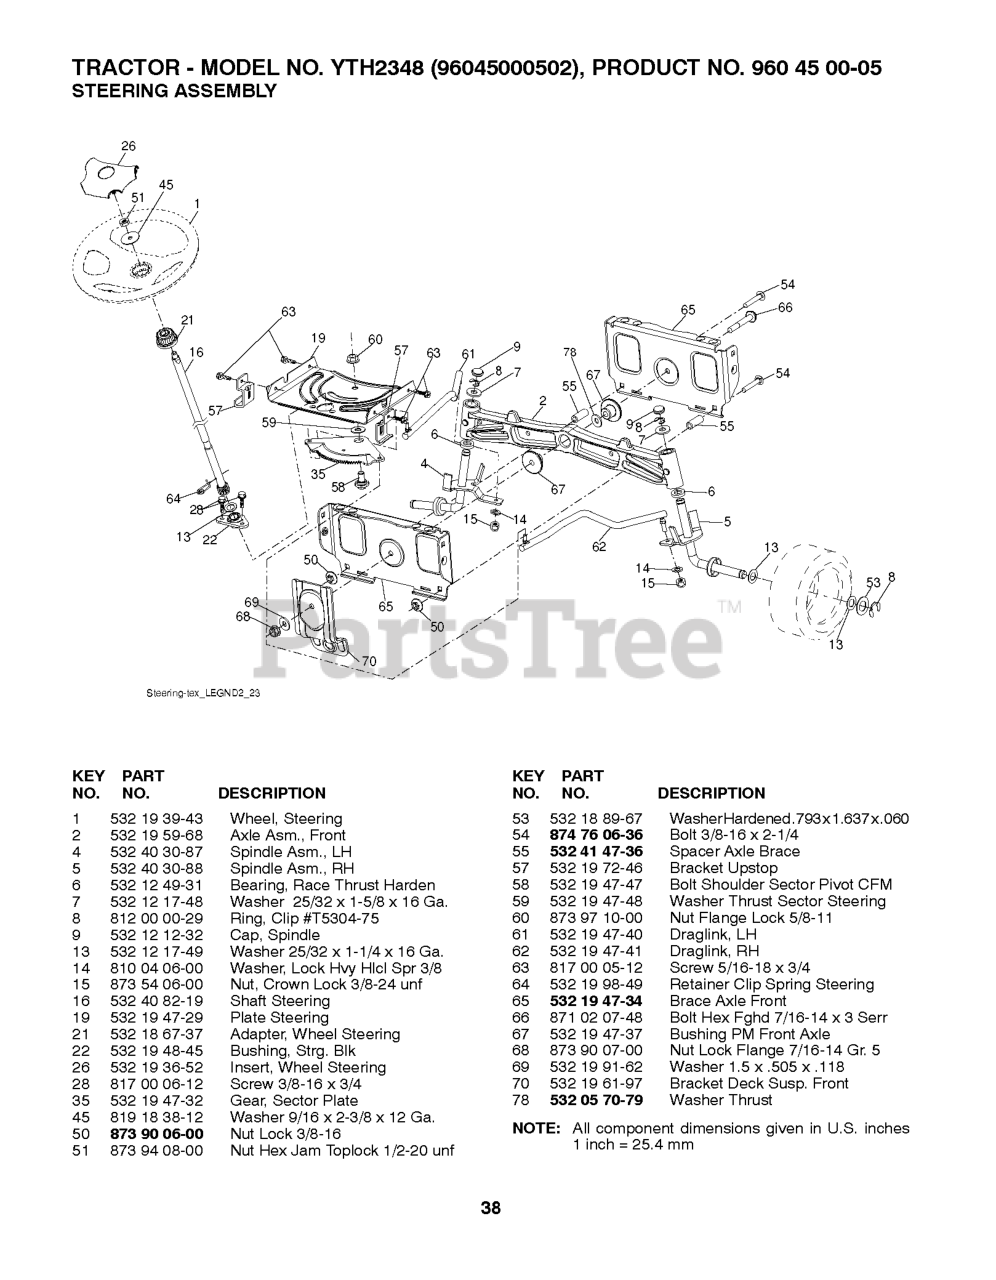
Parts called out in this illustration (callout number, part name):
1	WHEEL.STEERING.LEGEND2.GRY
2	AXLE.CAST.IRON
4	SPINDLE.WELDED.LH.15"TEX
5	SPINDLE.WELDED.RH.15"T
6	THRUST WASHER
9	CAP.SPINDLE.BLACK
14	WASHER, LOCK 3/8
15	NUT CROWNLOCK 3/8-24
16	SHAFT, STEERING
19	PLATE.STEER.DDL.NLT/NG
21	ADAPTER, WHEEL STNG..
22	BUSHING.ASM.STEERING.A
26	INSERT.CAP.STRG.WH.GRAY
28	SCREW, 3/8-16X3/4
35	GEAR.SECTOR.PLATE.DDL.
45	WASHER 9/16"ID, 2 3/8"OD
50	NUT LOCK FLG 3/8-16 UNC
51	NUT.HEX.1/2-20
53	WASHER.HARDENED
55	SPACER.BRACE.AXLE
57	BRKT.UPSTOP.GT/LT.TEX
58	BOLT.SHOULDER.SECTOR.P
59	WASHER.THURST.SECTOR.S
60	NUT FLANGE LOCK 5/8-11
61	DRAGLINK.LH.BALLSTUD.D
62	DRAGLINK.RH.BALLSTUD.D
63	SCREW
64	RETAINER.CLIP.SPRING.S
65	BRACE.AXLE.FRONT.NLT/N
66	BOLT HEX FGHD 7/16-14 X 3 SERR
67	BUSHING.PM.FRONT AXLE
68	NUT.LOCK.FLANGE.7/16
69	WASHER.1.5X.505X.118
70	BRKT.DECK.SUSPENSION.F
78	THRUST WASHER
